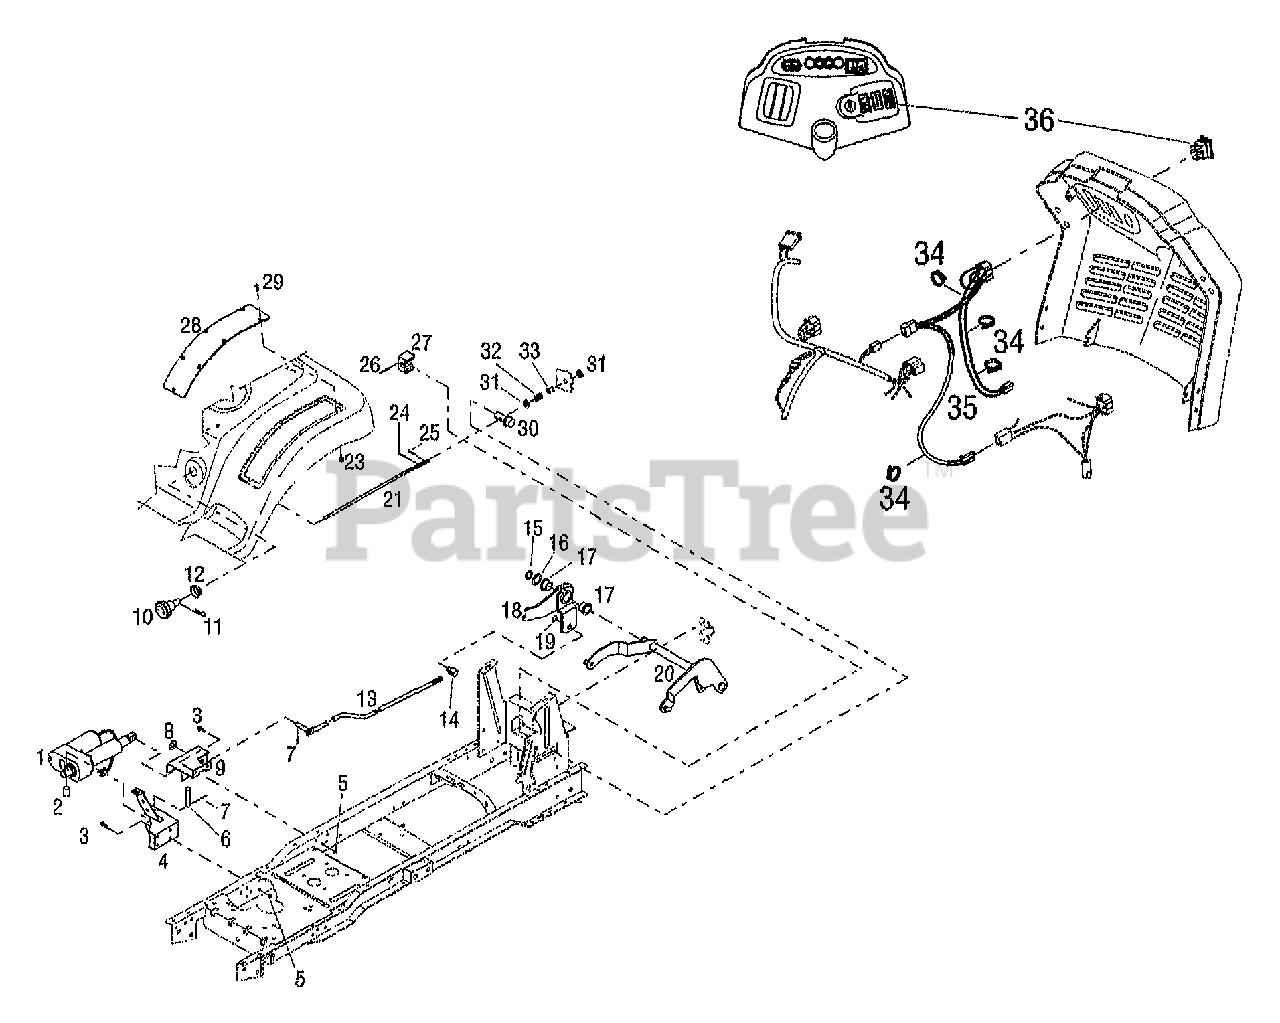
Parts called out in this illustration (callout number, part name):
3	SCR-HHC 5/16-18X.75 GR 5 ZP
4	SUPPORT-FRONT
5	NUT-HFLK 5/16-18 ZP
6	PIN-CLEVIS .5X2.75
7	PIN-COTTER .120X1.00 ZP
8	WASHER-1.06X.531X.1 ZP
9	SUPPORT-REAR
10	KNOB-HEIGHT ADJUST
11	PIN-HITCH
12	GROMMET-SNAP BUSHING
14	BLOCK-PIVOT
15	RING-HEAVY EXT HD 1.0 ID
16	WASHER-SPEC
18	ASSM-PIVOT ARM
19	RETAINING E-RING
21	SCR-HEIGHT ADJUST
23	NUT-LK 1/4-20
24	PIN-COTTER .125 X .75 ZP
25	PIN-ROLL .156X1.0
26	PIN-DRIVE
27	COLLAR-HEIGHT ADJUST
29	SCR-MACH .25-20X.62
30	BLOCK-HEIGHT ADJUST
32	SPRING-COMPRESSION
33	BUSHING-.5X.21 NYLON FLNG
34	TIE-CABLE NYLON BLACK
35	HARNESS-ACTUATOR
36	SWITCH-ROCKER
